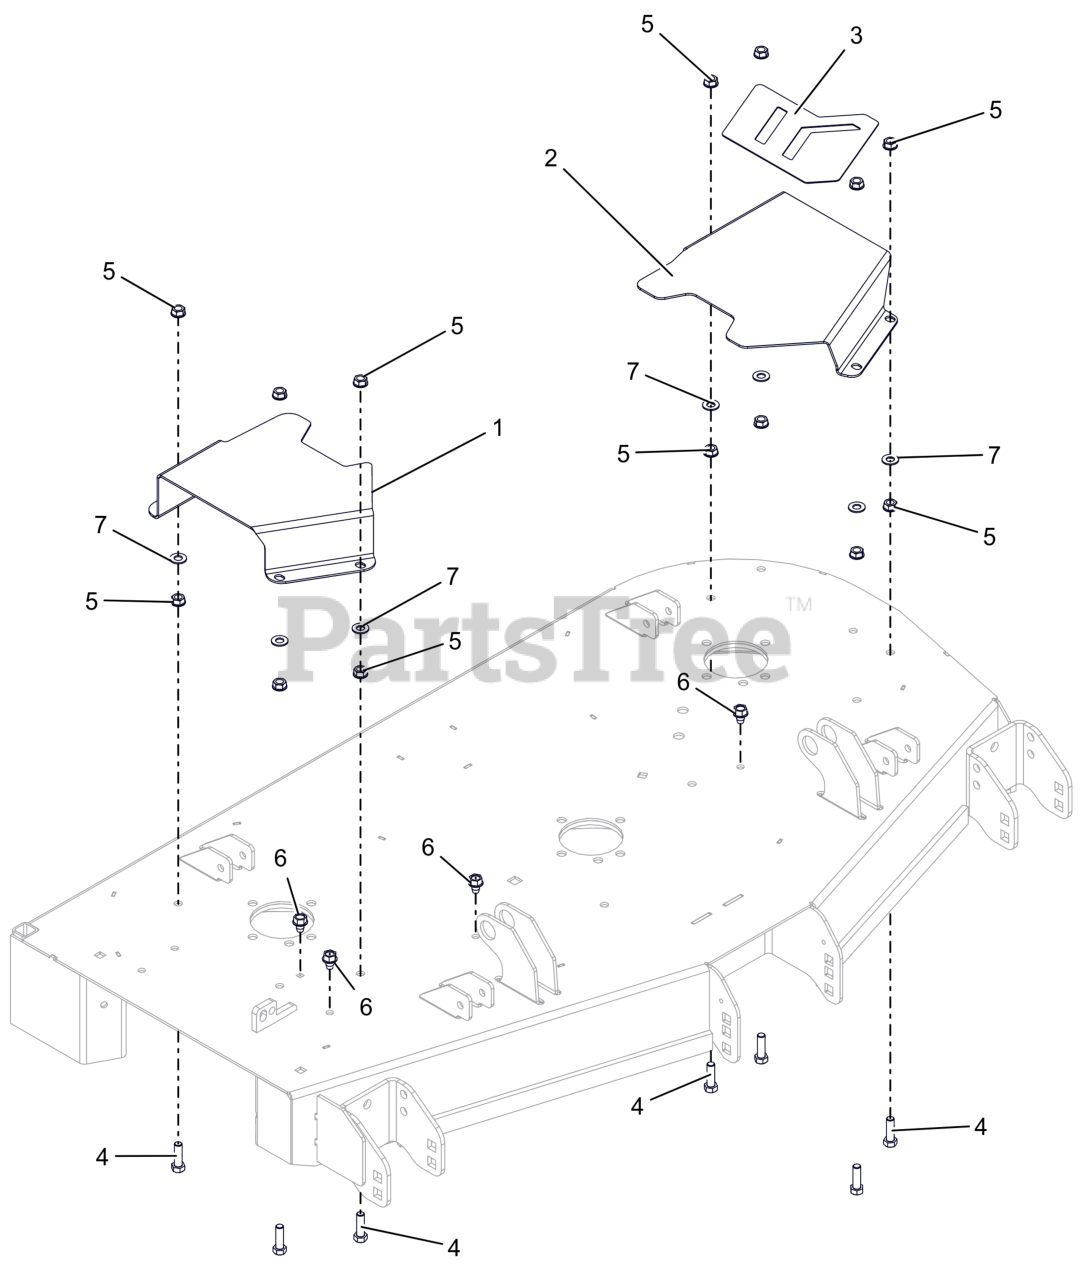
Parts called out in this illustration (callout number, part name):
1	COVER, BELT 48" RIGHT
2	COVER, BELT 48" LEFT
3	GRIP, TAPE 48 BELT COVER
4	BLT, HEX .38-16X1.25 G5 ZCC
5	NUT, SPNLK-FLG .38-16 G5 ZCC
6	SCR,TAP .375-16X.50 HWH TR ZCC
7	WSHR,FLT .406X.812X.065 ZCC
